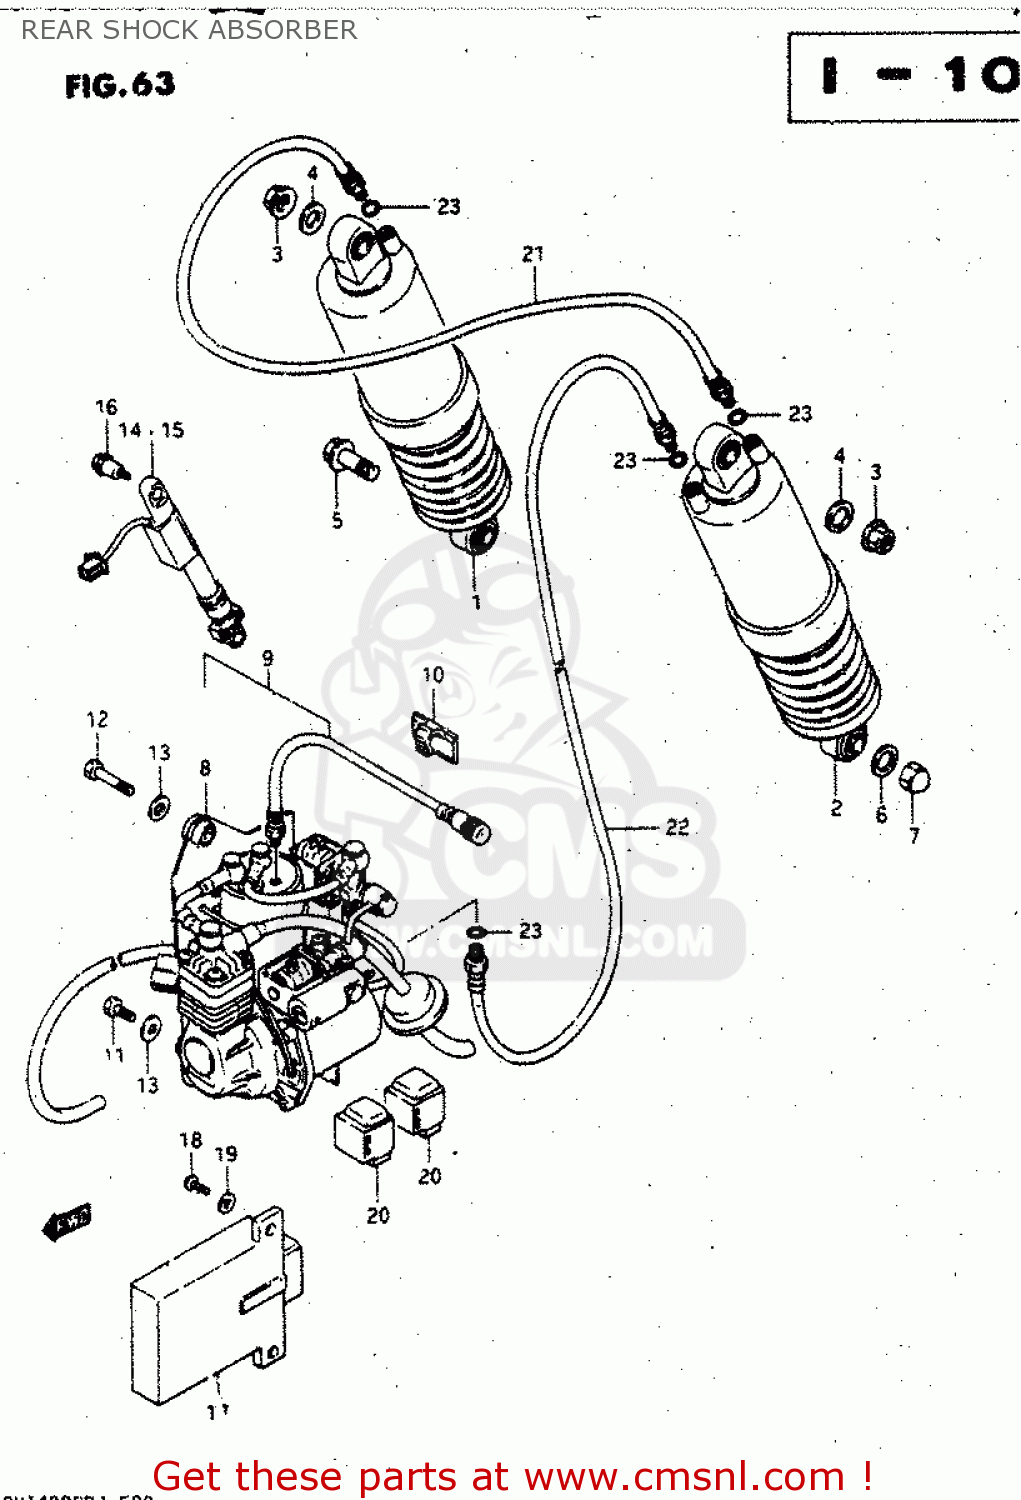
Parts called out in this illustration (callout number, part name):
1	ABSORBER ASSY,RR SHOCK,R
2	ABSORBER ASSY,RR SHOCK,L
3	NUT
4	WASHER
5	BOLT 2X33
6	WASHER
7	NUT
8	AUTO LEVEL ASSEMBLY,REAR SHOCK
9	AUTO LEVEL ASSEMBLY,REAR SHOCK
10	CLAMP
11	BOLT
12	BOLT
13	WASHER (6.5X20X1.2)
14	SENSOR ASSEMBLY,AUTO LEVEL
15	SENSOR ASSEMBLY,AUTO LEVEL
16	BOLT(6X21)
17	UNIT,AUTO LEVEL CONTROL
18	SCREW
19	WASHER
20	RELAY ASSY, MARKER LAMP
21	HOSE COMP,REAR SHOCK ABSORBER
22	HOSE COMP,AUTO LEVEL
23	O RING(D:1.9,ID:5.7)
